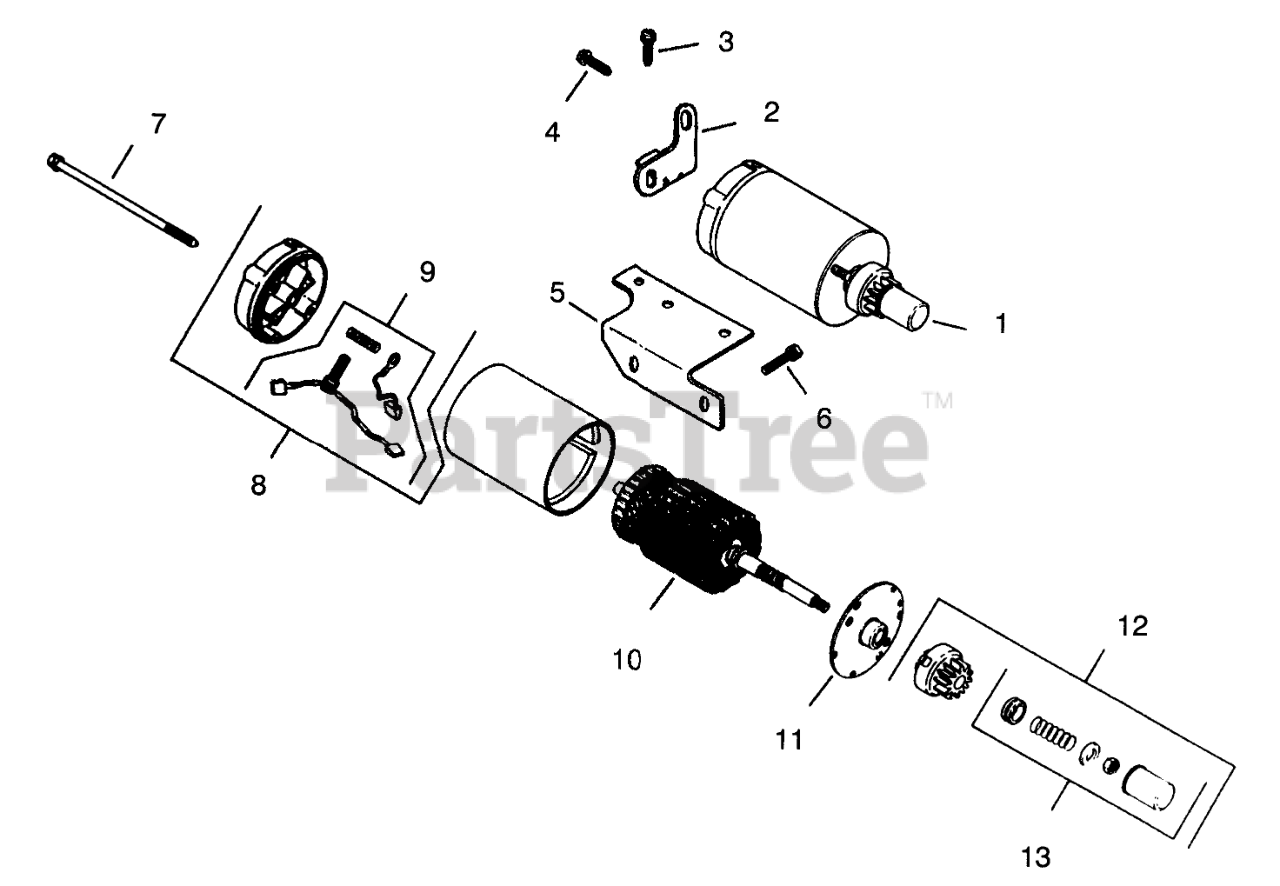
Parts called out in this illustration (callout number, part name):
1	Starter Assembly (Incl. Ref. #9-12)
2	Brace-Starter Tail
3	Screw
4	Screw-Hex. Hd.
5	Bracket-Starter
6	Screw
8	End Cap Ass-y (Incl . Ref. #9)
9	Brush Kit
10	Armature
11	Cap-Drive End
12	Kit-Drive (Incl. Ref. #15)
13	Drive Parts Kit
